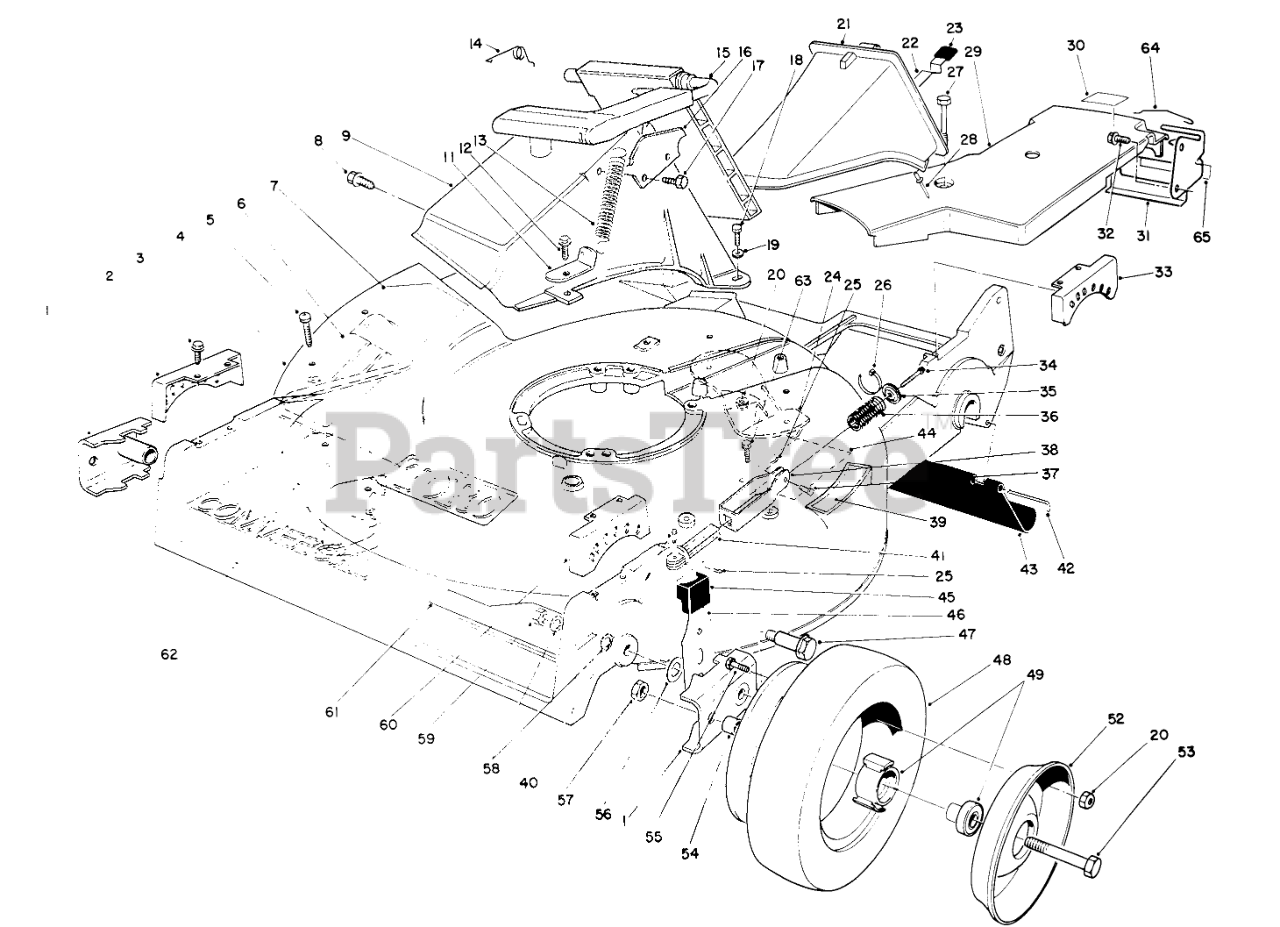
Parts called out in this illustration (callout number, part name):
1	ARM-PIVOT, FRONT
2	QUADRANT-FRONT, RH
3	SCREW-HWHTF
4	Housing-Commercial (Incl. Ref. #5-7, 24, 44, & 62 pg.1-2) (Incl. Ref. #28 pg. 4)
5	SCREW-PPH
6	KICKER-RH
7	DECAL-DANGER
8	SCREW AND WASHER ASM
9	DISCHARGE TUNNEL
11	BRACKET-SPRING
12	SCREW-HWH
13	SPRING-DOOR
14	RETAINER-DOOR
15	DOOR ASSEMBLY
16	DOOR LATCH PLATE
17	SCREW-PLASTITE
18	SCREW-HH
19	WASHER-FLAT
20	NUT-LOCK, NI
21	Plug-Discharge (Incl. Ref. #22, 23, & 28)
22	LATCH-PLUG, DISCHARGE
23	GRIP-LATCH
24	KICKER-REAR
25	PIN-COTTER
26	TIE-CABLE
27	SCREW-HHFTF
28	RIVET-HEAD, FLAT
29	BELT COVER (MACHINED)
30	LABEL-GREASE
31	BRACKET-ADJUSTMENT, TRACTION
32	SCREW-HWHTF
33	QUADRANT-REAR, LH
34	SCREW-HWHTF
35	RETAINER-SPRING
36	SPRING
37	PIN-CABLE
38	Bracket-Spring
39	STEP PAD DECAL
40	PIN-SPRING
41	GUIDE-SPRING
42	ROD-SHIELD
43	SHIELD-TRAILING
44	DECAL - DANGER, COVERS
45	KNOB-ARM
46	FRONT SPRING ARM ASM
47	BOLT-WHEEL
49	Hub Ass-y
52	Wheel-Half
53	SCREW-HH
54	SPACER-WHEEL
55	SCREW-HH
56	WASHER-THRUST
57	NUT-LOCK, CONE
58	WASHER
59	NUT-LOCK
60	QUADRANT-FRONT, LH
61	DECAL - RECYCLER
62	KICKER-FRONT
63	SCREW-HH
64	RETAINER-CABLE
65	DECAL-POSITION, GEAR
